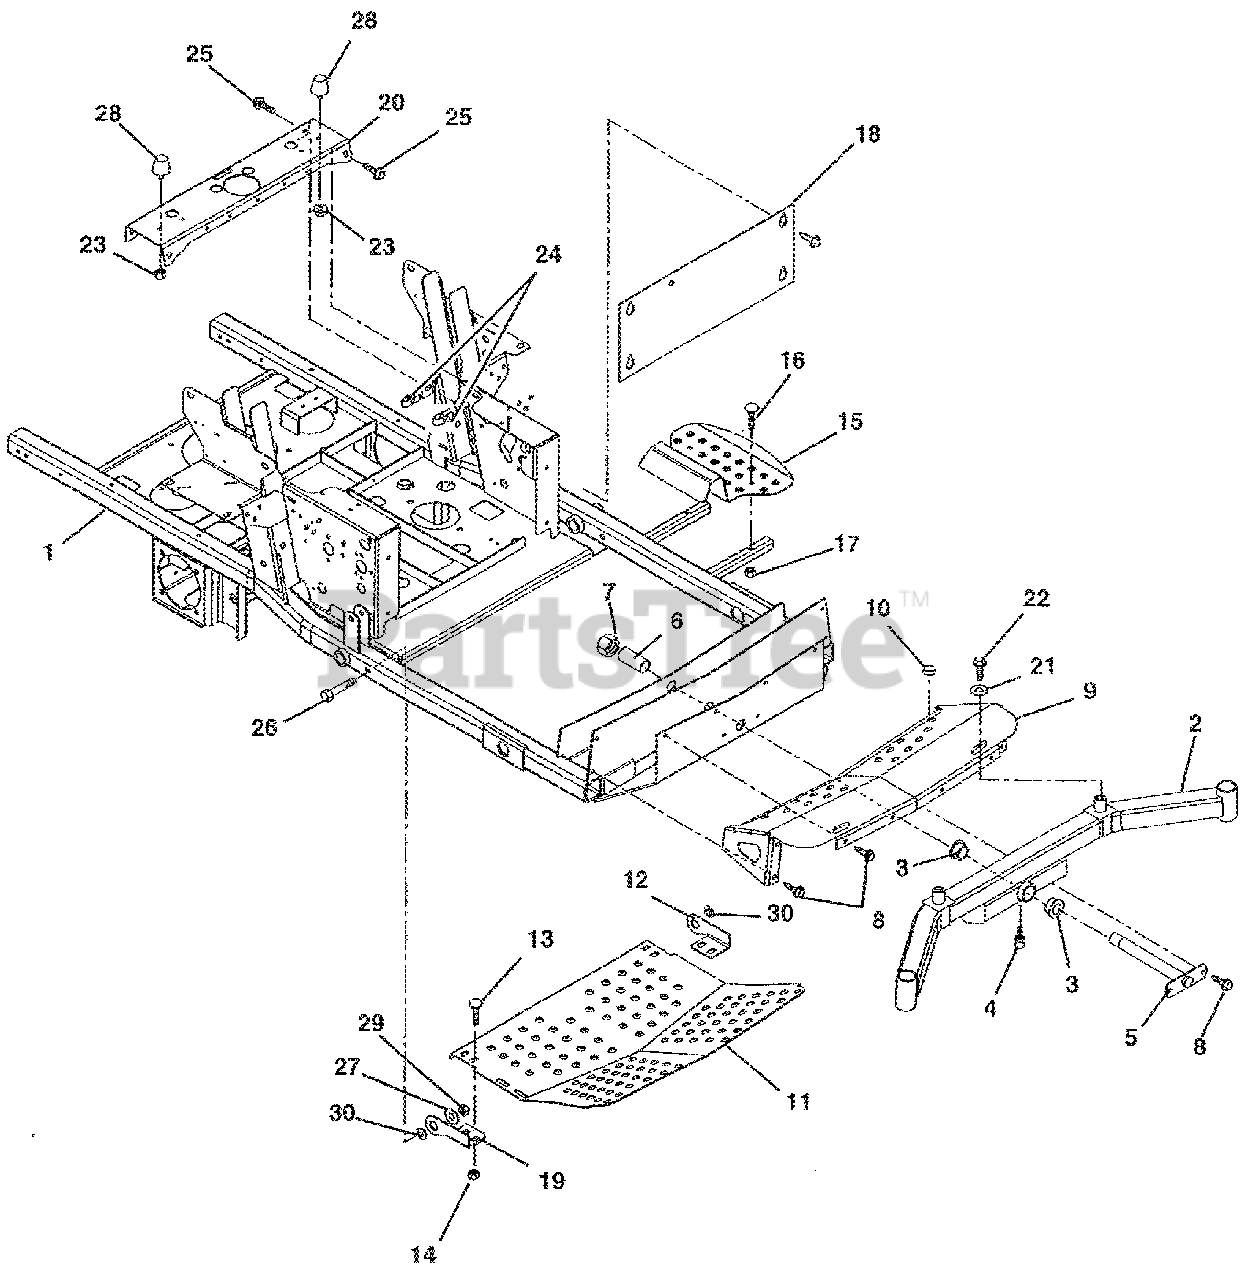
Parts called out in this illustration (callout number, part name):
1	Weldment, Frame
2	Weldment, Axle
3	Bushing, Flange 1.02 x 1.385 x .75 x 1.75
4	Fitting, Lube .25-28 x .256
5	Pin, Axle
7	Nut, Locking Nylon 1.00-14
8	Screw, Tapping .38-16 x .75
9	Weldment, Axle Cover
10	Button, Bumper
11	Panel, Inspection
12	Hinge, Footboard Left Hand
13	Bolt, Round Head Square Neck .38-18 x 1.00 Grade 5
14	Nut-Locking-Top-Flange .38-16
15	Step, Ingress
16	Bolt, Round Head Square Neck, .31-18 x 1.75 Grade 5
17	Nut, Locking Top Flange .31-18
18	Plate, Kick
19	Hinge, Footboard Right Hand
20	Channel, Cross
21	Washer, Flat Steel .518 x 2.00 x .105
22	Bolt, Hex .50-20 x 1.00 Grade 5
23	Nut, Locking Flange .312-24
24	Nut, Retainer .375-16 x .37
25	Bolt, Serrated Hex Flange Washer Head .38-16 x 1.00
26	Bolt, Hex .50-13 x 3.25 Grade 5
27	Washer, Flat Steel .563 x 1.38 x .109
29	Nut-Locking-Top-Flange .50-13
30	Bushing, Flange .515 x .75 x .275 x 1.12
